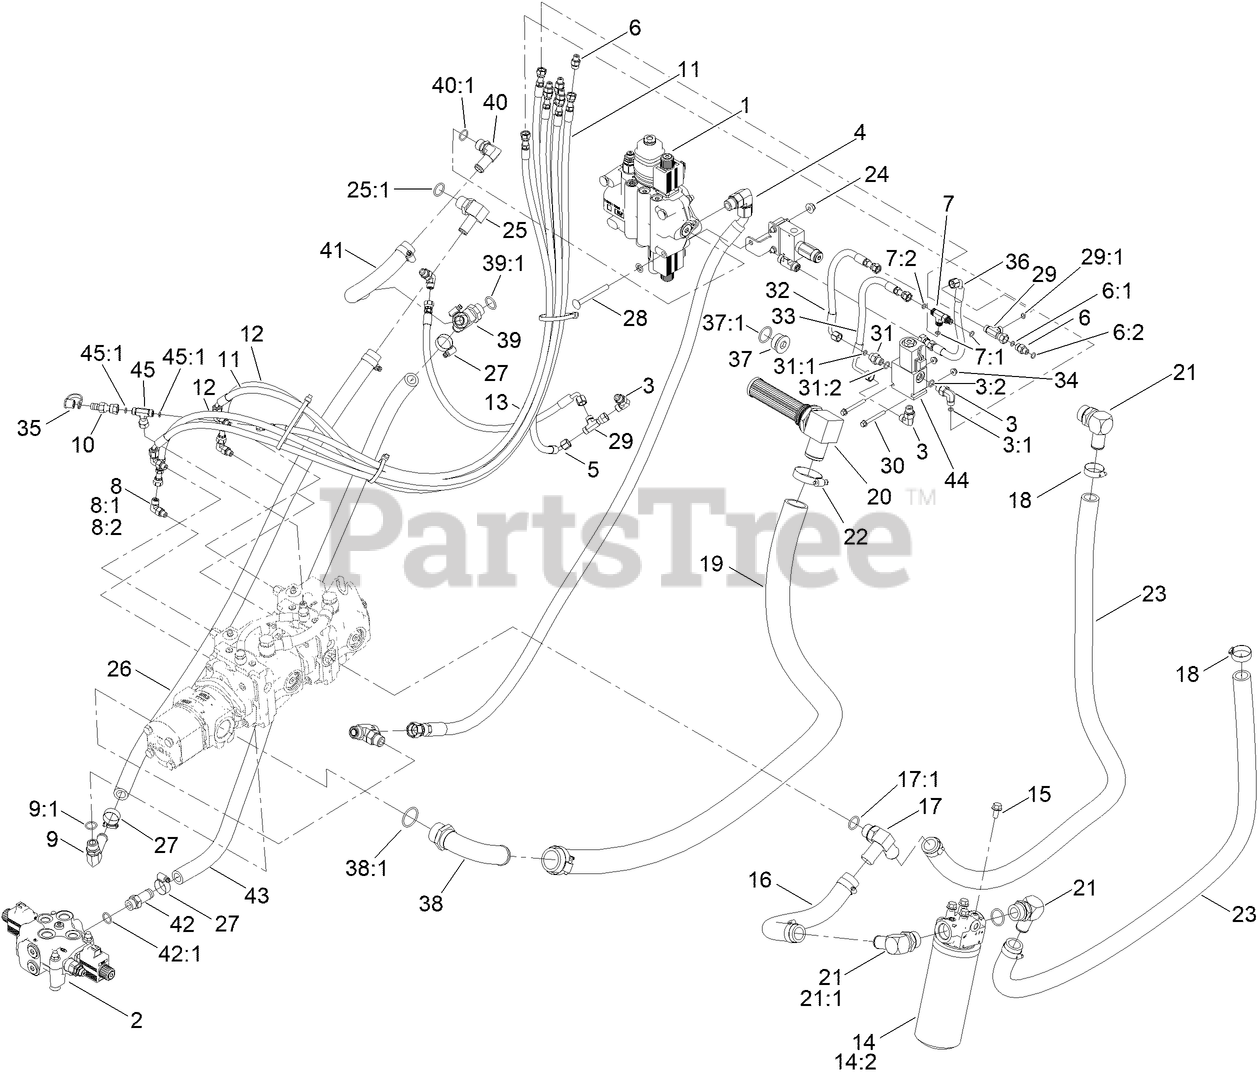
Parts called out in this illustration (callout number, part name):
1	LOADER VALVE ASM,
2	VALVE-AUX
3	FITTING-ELBOW, 90 DEG
3:1	O-RING
3:2	O-RING
4	HYD HOSE ASM
5	HYD HOSE ASM
6	FITTING-STRAIGHT
6:1	O-RING
6:2	O-RING
7	FITTING-TEE
7:1	O-RING
7:2	O-RING
8	FITTING-ELBOW, 90 DEG
8:1	O-RING
8:2	O-RING
9	FITTING-90
9:1	O-RING
10	NIPPLE-TEST
11	HYD HOSE ASM
12	HYD HOSE ASM
13	HYD HOSE ASM
14	FILTER HEAD ASM
14:2	ELEMENT-FILTER
15	SCREW-HHF
16	HYD HOSE ASM
17	CONNECTOR
17:1	O-RING
18	CLAMP-HOSE
19	HYD HOSE ASM
20	STRAINER FITTING ASM
21	STEM-BARB-90
21:1	O-RING
22	CLAMP-HOSE
23	HYD HOSE ASM
24	NUT-HF, NI
25	FITTING-ELBOW, 90
25:1	O-RING
26	HYD HOSE ASM
27	CLAMP-HOSE
28	SCREW-CARR
29	FITTING-HYD
29:1	O-RING
30	SCREW-HHF
31	FITTING-STRAIGHT
31:1	O-RING
31:2	O-RING
32	HYD HOSE ASM
33	HYD HOSE ASM
34	NUT-HF
35	CAP-DUST
36	HYD HOSE ASM
37	FITTING-PLUG
37:1	O-RING
38	ELBOW-SUCTION,
38:1	O-RING
39	FITTING-45 DEG
39:1	O-RING
40	STEM - 90 Bead Hose 3/4 ID x 7.8 - 14
40:1	O-RING
41	HYD HOSE
42	FITTING-STR
42:1	O-RING
43	HYD HOSE ASM
44	SOLENOID VALVE
45	FITTING-TEE
45:1	O-RING
